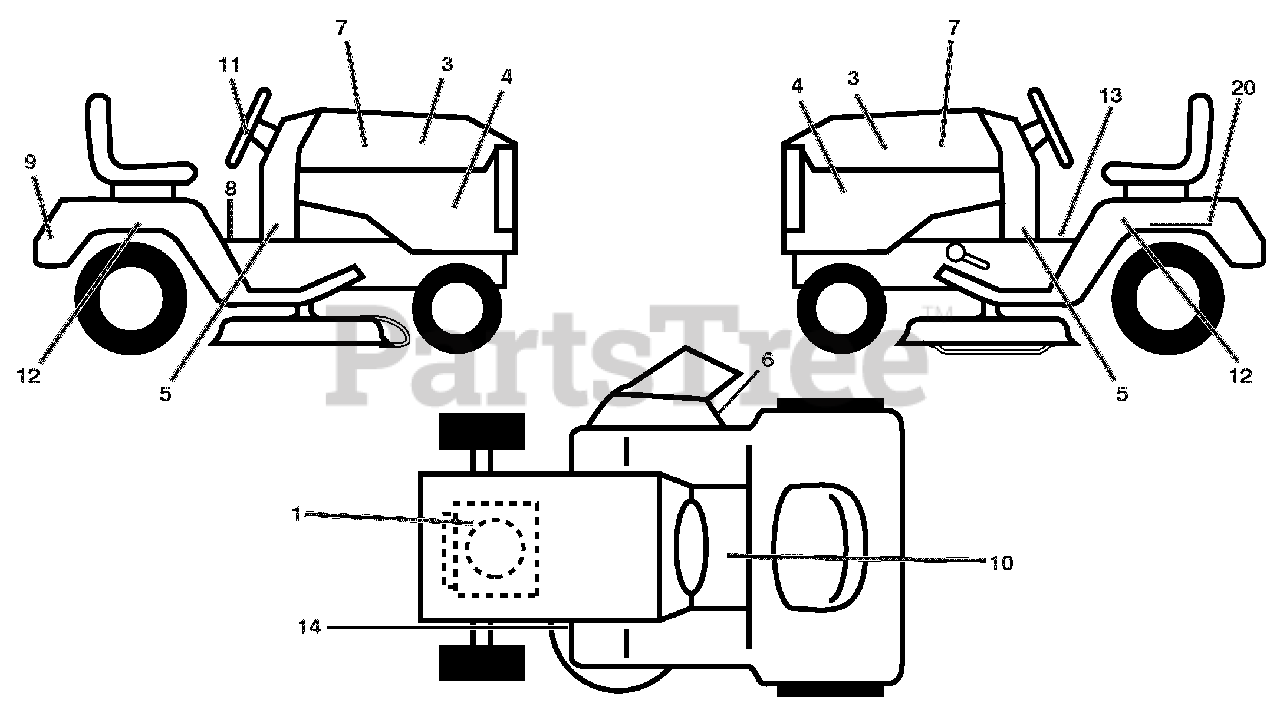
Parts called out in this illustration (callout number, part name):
1	DECAL ENGINE H.P.
3	DECAL.HOOD.LH/RH.
4	DECAL.SDPNL.PWRDBY B&S.ARIENS
5	DECAL.DASH.LWOWER.20HP.ARIENS
6	DECAL.MOWER.WARN.KEEP HAND AWY
7	DECAL.REPLACEMENT
8	DECAL.FENDER.WARNING.ENG/FR.07
9	DECAL.FENDER.REAR.ARIENS
10	DECAL, WARNING START INST.
11	DECAL.WHEEL.STEER.ARIENS
12	DECAL.FENDER.SIDE.HYDRO.ARIENS
13	DECAL.FENDER
14	DECAL.V-BELT.SCH.42/46"MEC/ELE
20	DECAL.BAT.DAN/POI P/L SYM.WPN
